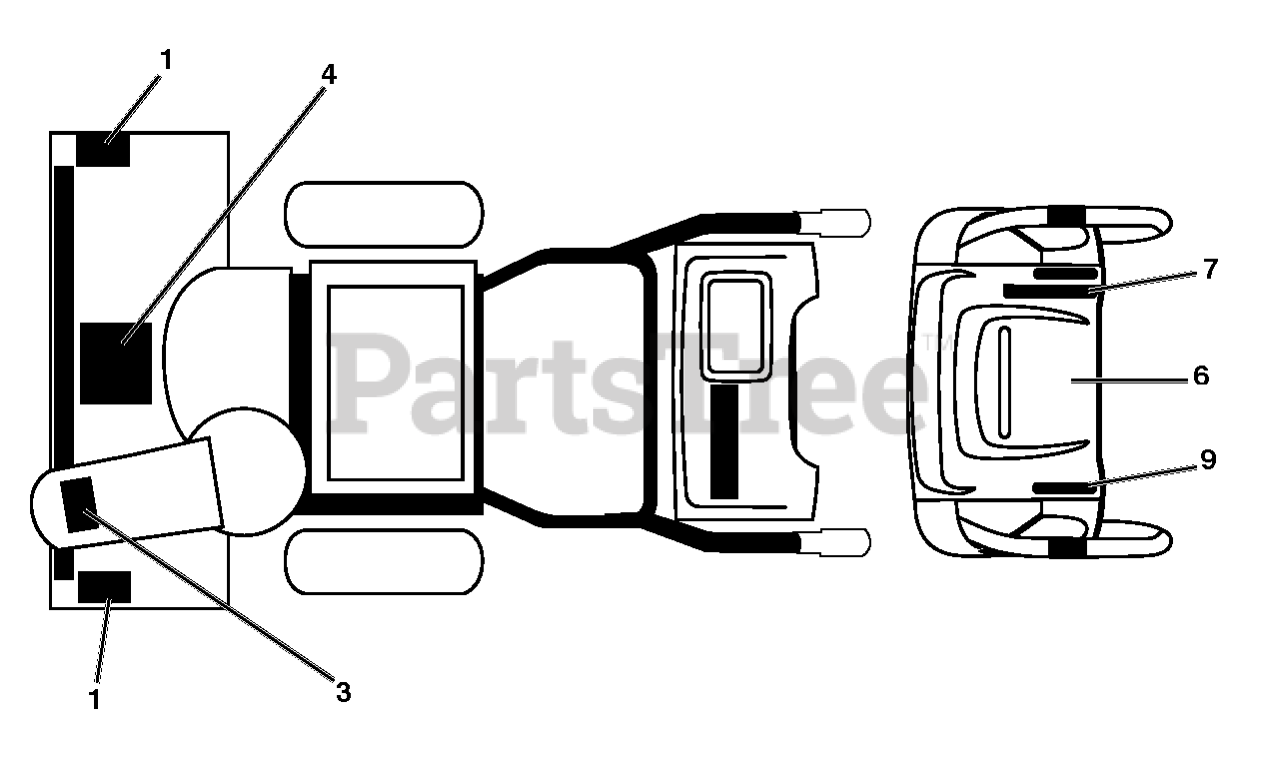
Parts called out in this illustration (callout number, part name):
1	DECAL.SNOWTHR.AUGER
3	DECAL.SNOWTHR.CHUTE.SAFETY
4	DECAL.SNOWTR.READ.OWN.MAN.E/F
6	DECAL.CONSOLE.SNOW.INST.ENG/FR
7	DECAL.CONS.RT.SPD/LEV/PWRST.
9	DECAL.CONS.LT.SPD/LEV/PWRST.
